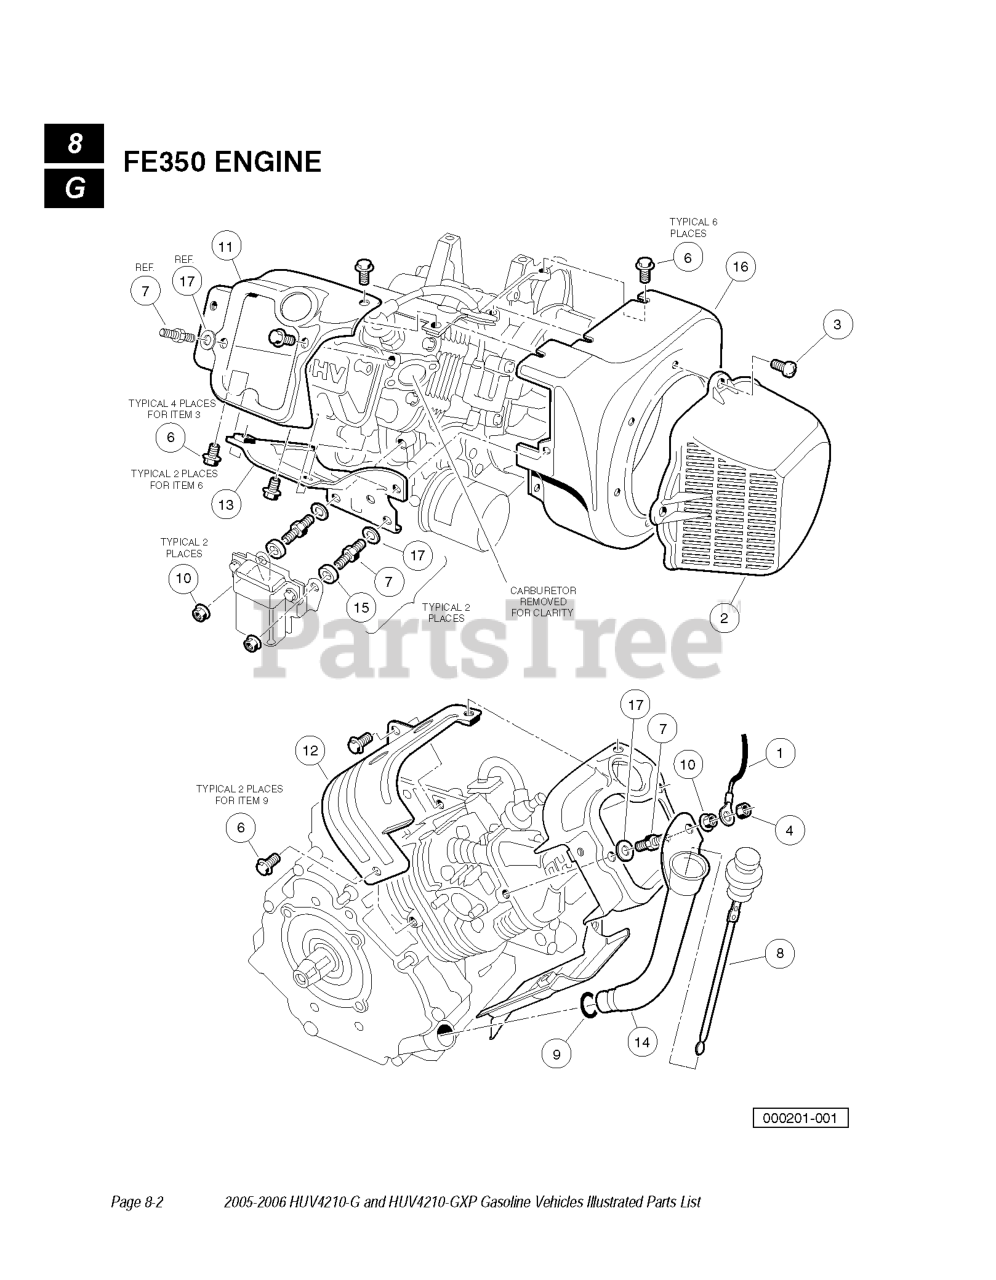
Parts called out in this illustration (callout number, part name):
1	WIRE ASM
2	SHROUD, FAN
3	SCREW, M6-1.00 X 10MM PAN HD
4	LOCKNUT, M6-1.00 NYLON INSERT
5	ENGINE, FE350 (CW) W/O CR
6	BOLT, FLANGED
11	SHROUD ENGINE
12	SHROUD - ENGINE
13	SHROUD ENGINE
14	OIL FILLER TUBE
15	SPACER 6.50 X 12 X 5.5
16	HOUSING, FE350 FAN
